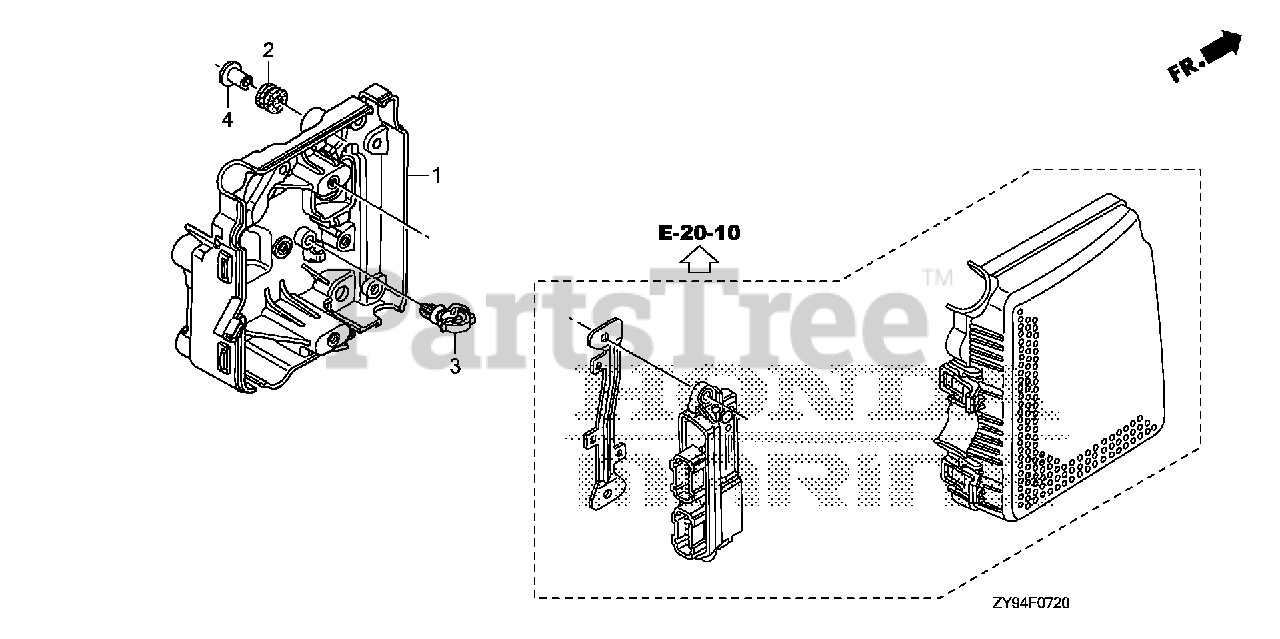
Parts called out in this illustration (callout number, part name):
1	CASE, ELECTRONIC PARTS
2	GROMMET, ELECTRONIC PARTS CASE
3	CLIP, WIRE HARNESS
4	COLLAR, MODULE IGNITION CONTROL CASE (CDI)
